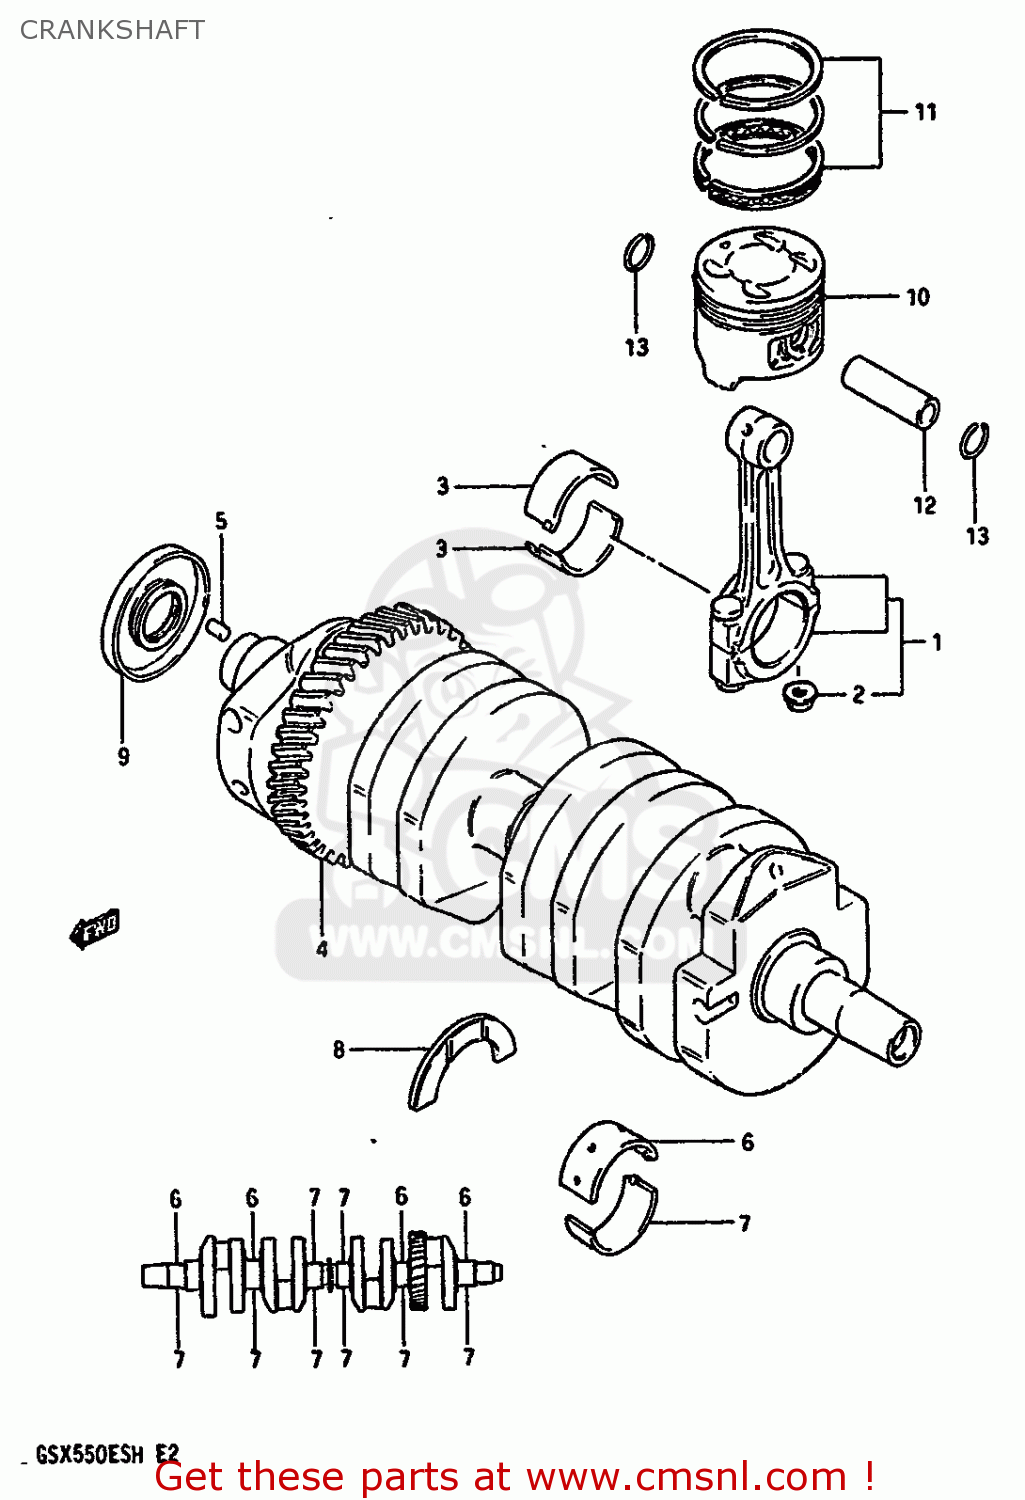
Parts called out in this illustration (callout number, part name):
1	ROD ASSEMBLY,CONNECTING
2	NUT
3	BEARING,CRANK PIN
4	CRANKSHAFT ASSEMBLY
5	PIN
6	BEARING,CRANKSHAFT
7	METAL,CRANKSHAFT
8	PLATE,CRANK THRUST
9	OIL SEAL
10	PISTON
11	RING SET,PISTON
12	PIN,PISTON
13	CIRCLIP
